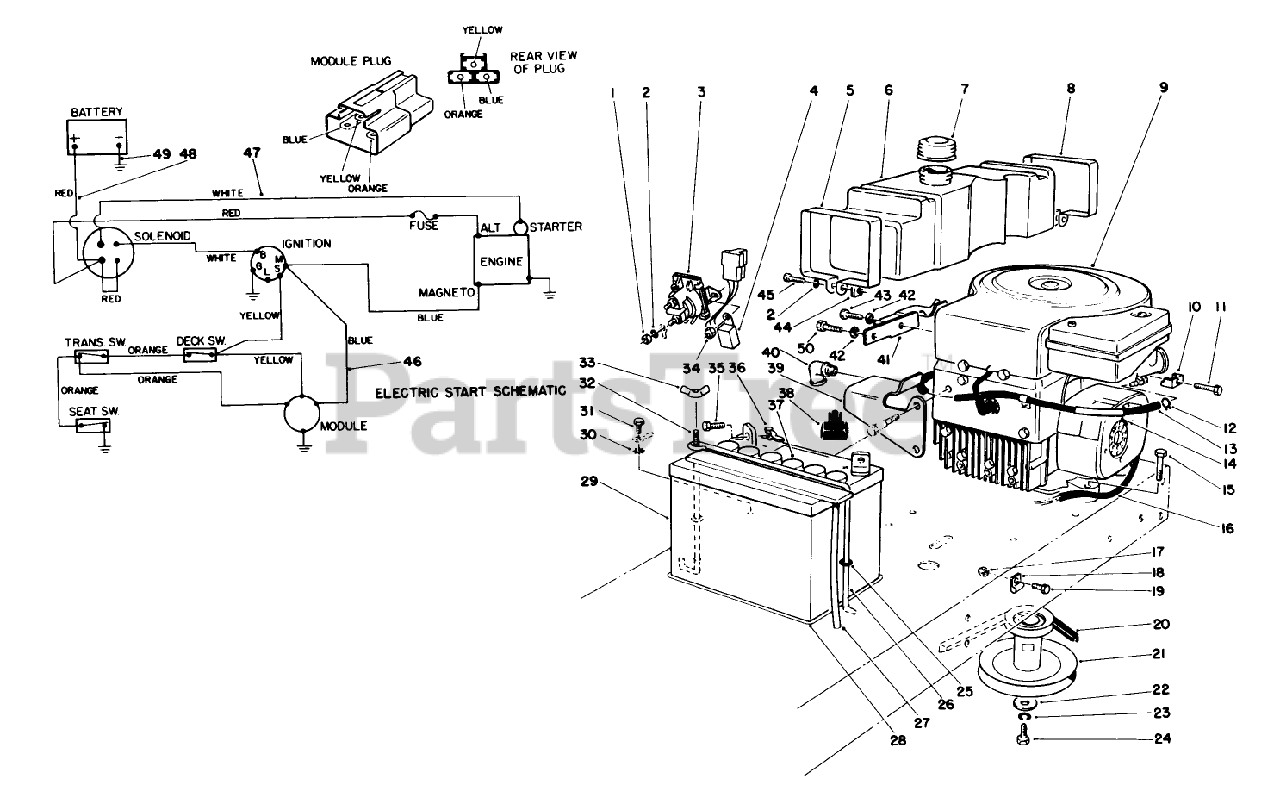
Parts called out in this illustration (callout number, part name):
1	NUT-JAM
2	WASHER-LOCK
6	TANK-5 QT GAS
7	GAS CAP ASM
9	Engine
10	CLAMP-CASING
11	SCREW (F/W ENGINE)
12	CLAMP-HOSE
14	SUPPORT-FUEL LINE
15	SCREW-HH
17	NUT-LOCK, NI
18	CLAMP
19	SCREW-HH
20	V-BELT, TRACTION
21	PULLEY
22	WASHER-FLAT
23	WASHER-LOCK
24	SCREW-HH
25	O-RING
26	HOLDDOWN-BATTERY
27	TUBE-BATT DRAIN/80-2600
28	PAD-SKID, ANTI
30	WASHER-LOCK, INTERNAL
31	SCREW-HHF
33	NUT-WING
34	NUT-LOCK, CONE
35	SCREW-HH
36	NUT-WING
37	CAP-BATTERY
38	BOOT-TERMINAL
40	ELBOW-STREET, 90 DEG
41	REAR TANK MTG BRKT *B
42	WASHER-PLAIN
43	SCREW-HH
44	NUT-SQUARE
45	SCREW-HSH
48	WIRE ASM
49	WIRE ASM(BATT/GRD.
50	SCREW-HH
